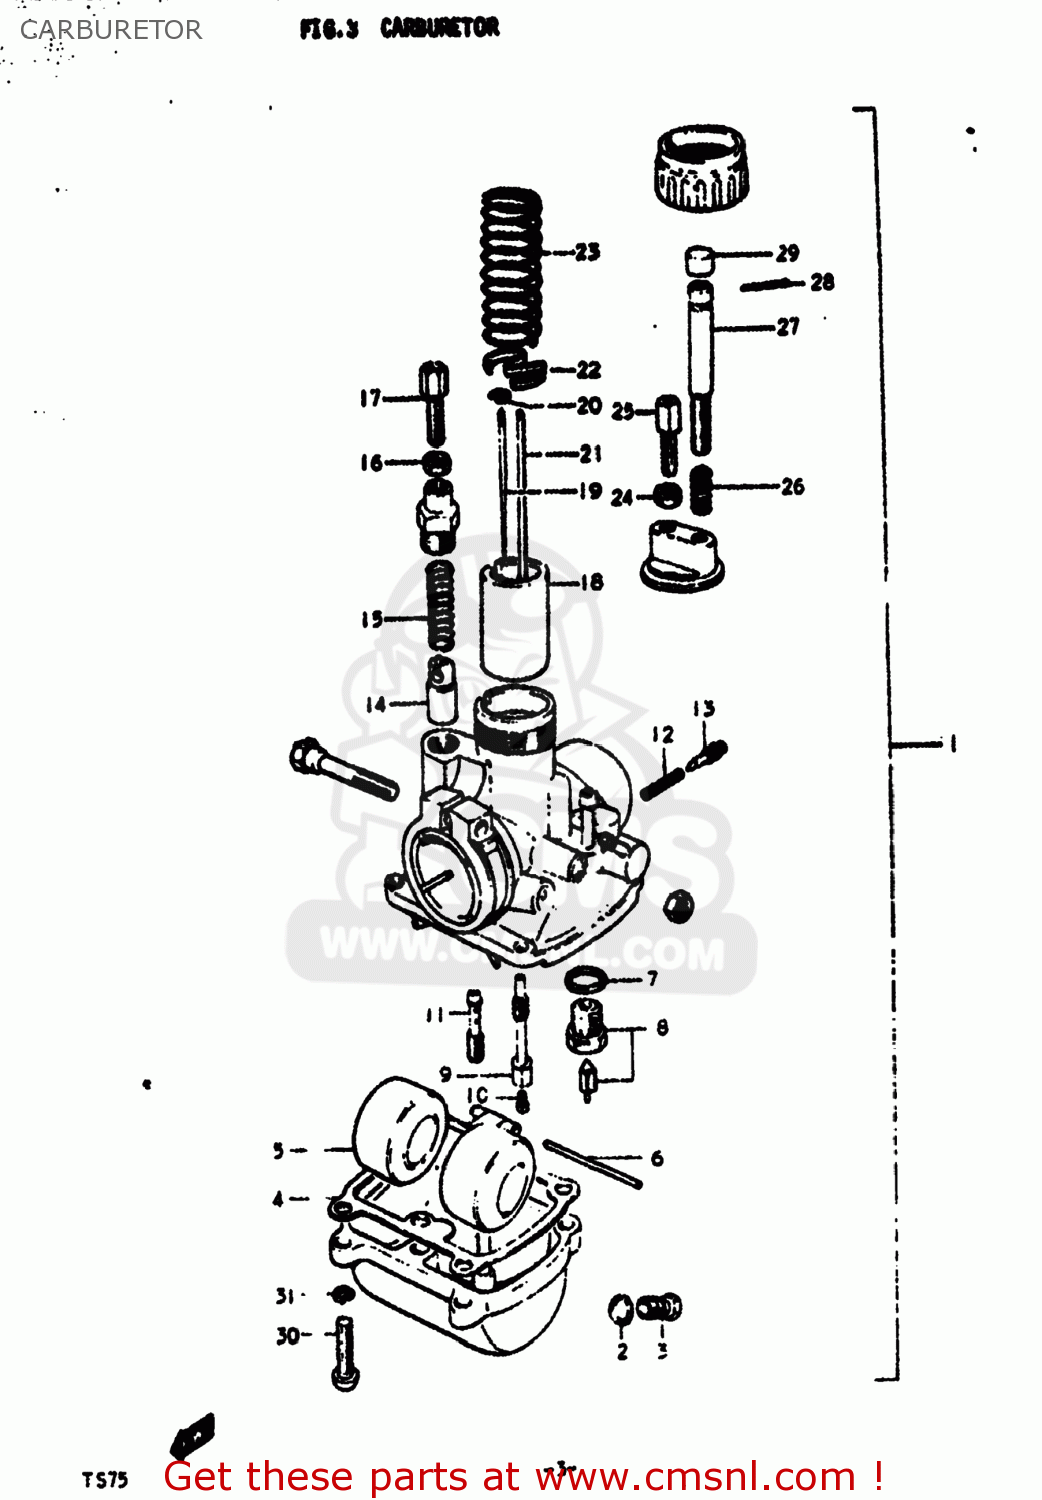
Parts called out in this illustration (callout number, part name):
1	CARBURETOR ASSEMBLY
2	GASKET,DRAIN,PLUG (NAS)
3	PLUG
4	GASKET,FLOAT CHAMBER (NAS)
5	FLOAT
6	PIN,FLOAT
7	GASKET,NEEDLE VALVE (NAS)
8	VALVE ASSEMBLY,NEEDLE
9	JET,NEEDLE
10	JET
11	JET
12	SPRING
13	SCREW,PILOT AIR
14	PLUNGER,STARTER
15	SPRING
16	NUT
17	ADJUSTER,CABLE
18	VALVE,THROTTLE
19	NEEDLE,JET
20	CLIP,NEEDLE
21	ROD,THROTTLE VALVE STOP
22	PLATE,THROTTLE VALVE
23	SPRING,THROTTLE VALVE
24	NUT
25	ADJUSTER,CABLE
26	SPRING
27	SCREW,THROTTLE STOP
28	PIN 12X10
29	CAP,THROTTLE VALVE STOP SCREW
30	SCREW
31	LOCK WASHER
